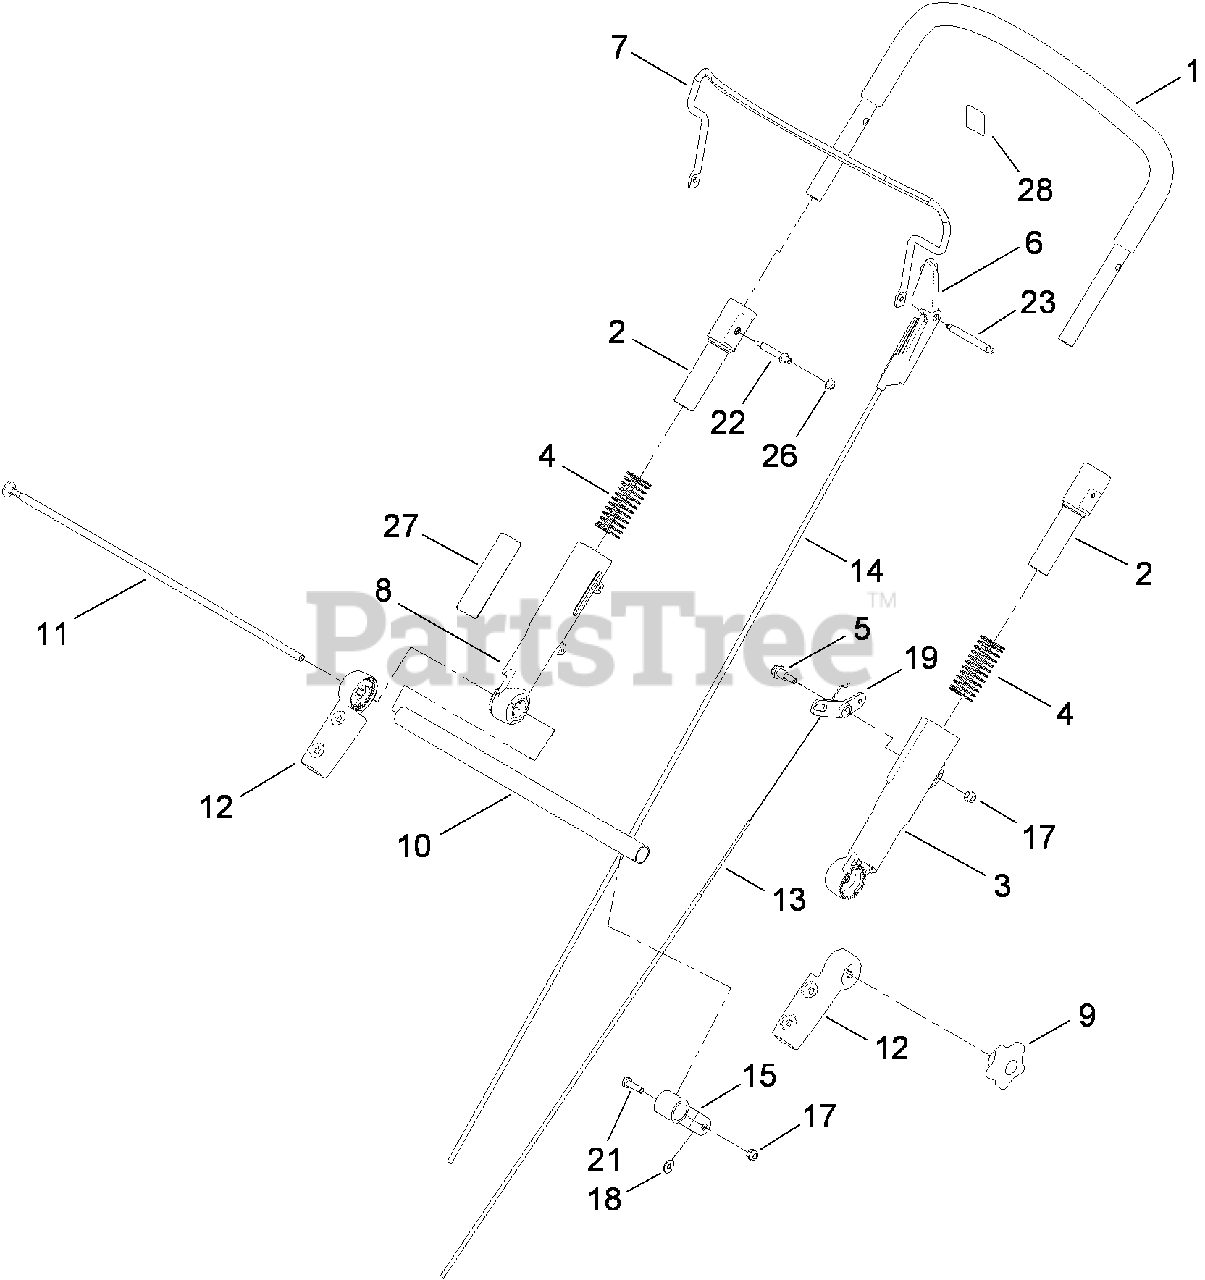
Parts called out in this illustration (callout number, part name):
1	UPPER HANDLE ASM
2	SLEEVE-INNER
3	SLEEVE-OUTER, LH
4	SPRING-COMPRESSION
5	BOLT-SHOULDER
6	STOP-PIVOT
8	SLEEVE-OUTER, RH
11	ROD-THREADED
12	MOUNT-HANDLE, LOWER
13	CABLE-TRACTION
14	CABLE-BRAKE
15	CLAMP-CABLE
17	NUT-LOCK, NI
18	WASHER-FLAT
19	LEVER-TRACTION
21	SCREW-HH
22	PIN-HANDLE
23	PIN-BAIL, LH
26	RETAINER-PUSH ON
28	DECAL-HANDLE, POSITION
